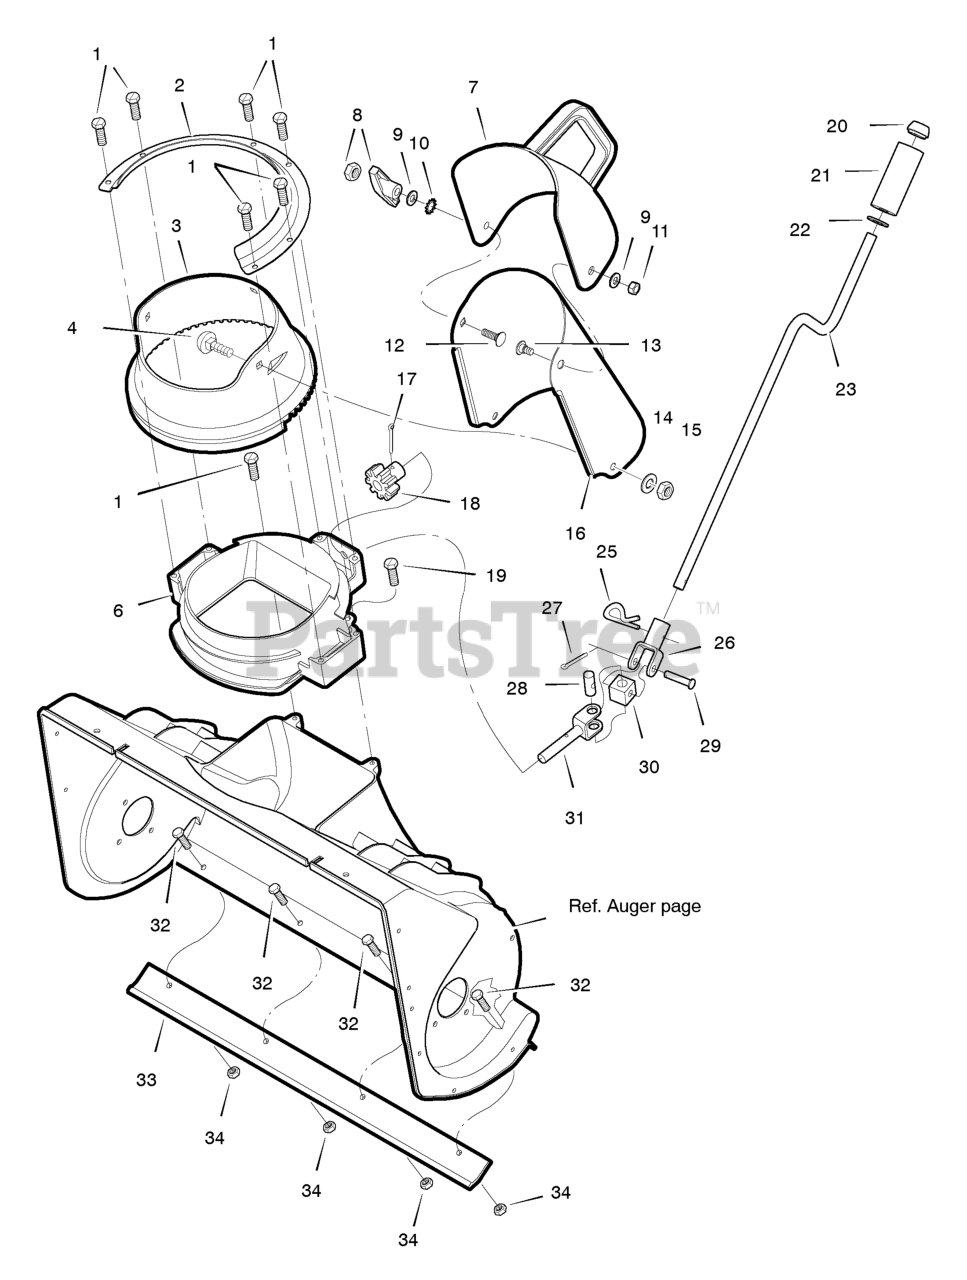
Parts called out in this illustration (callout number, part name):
1	Screw 1/4-14
2	Retainer, Chute Ring
3	Ring, Chute
4	Bolt, Carriage 5/16-18 x .75
6	Neck, Chute
7	Chute, 22" Upper
9	Washer
10	Lockwasher, Shakeproof
11	Locknut, Hex 5/16-18
12	Bolt, Carriage 5/16-18
13	Bolt, Upper Chute
14	Washer
15	Nut
16	Chute, Lower
17	Pin, Cotter
18	Gear, 9-Tooth
19	Screw, 1/4-14 x .75
20	Nut, Push
21	Knob, Sleeve
22	Washer
23	Crank, Chute Rotation
25	Pin, Hair
26	Yoke Assembly, Adapter
27	Pin, Cotter
28	Pin, Universal Joint
29	Pin, Clevis
30	Housing, Universal
31	Rod, Lower Crank
32	Screw 1/4-20 x .75
33	Blade, Scraper
34	Locknut, Hex 1/4-20
